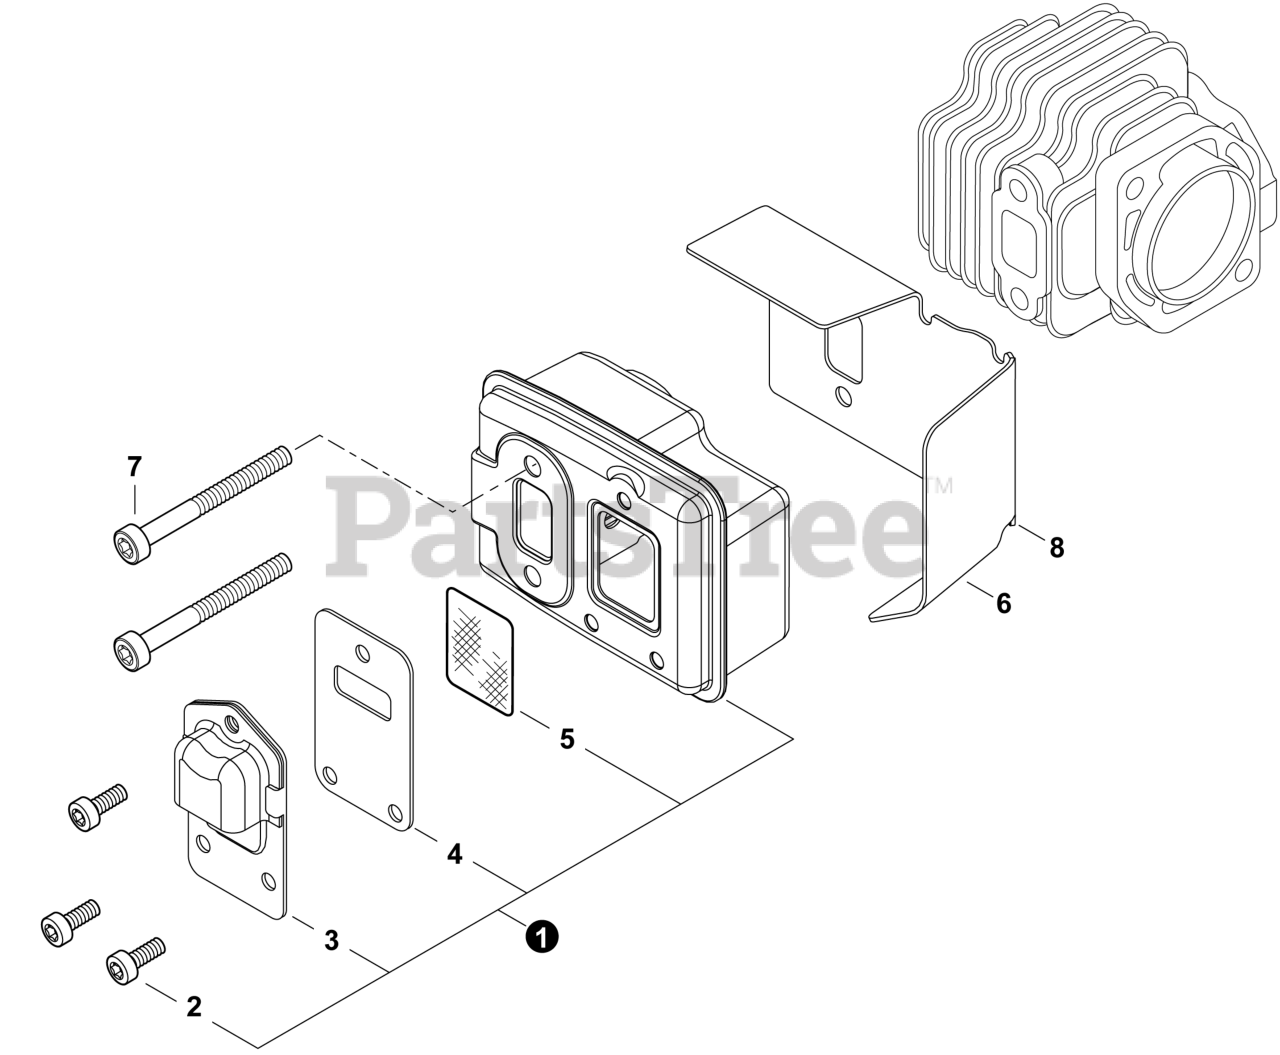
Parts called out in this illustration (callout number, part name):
1	MUFFLER ASSY
2	BOLT, TORX 4x8
3	GUIDE, EXHAUST
4	GASKET, EXHAUST
5	SCREEN, SPARK ARRESTER
6	HEAT SHIELD, EXHAUST
7	BOLT, TORX 5x50
8	GASKET KIT
